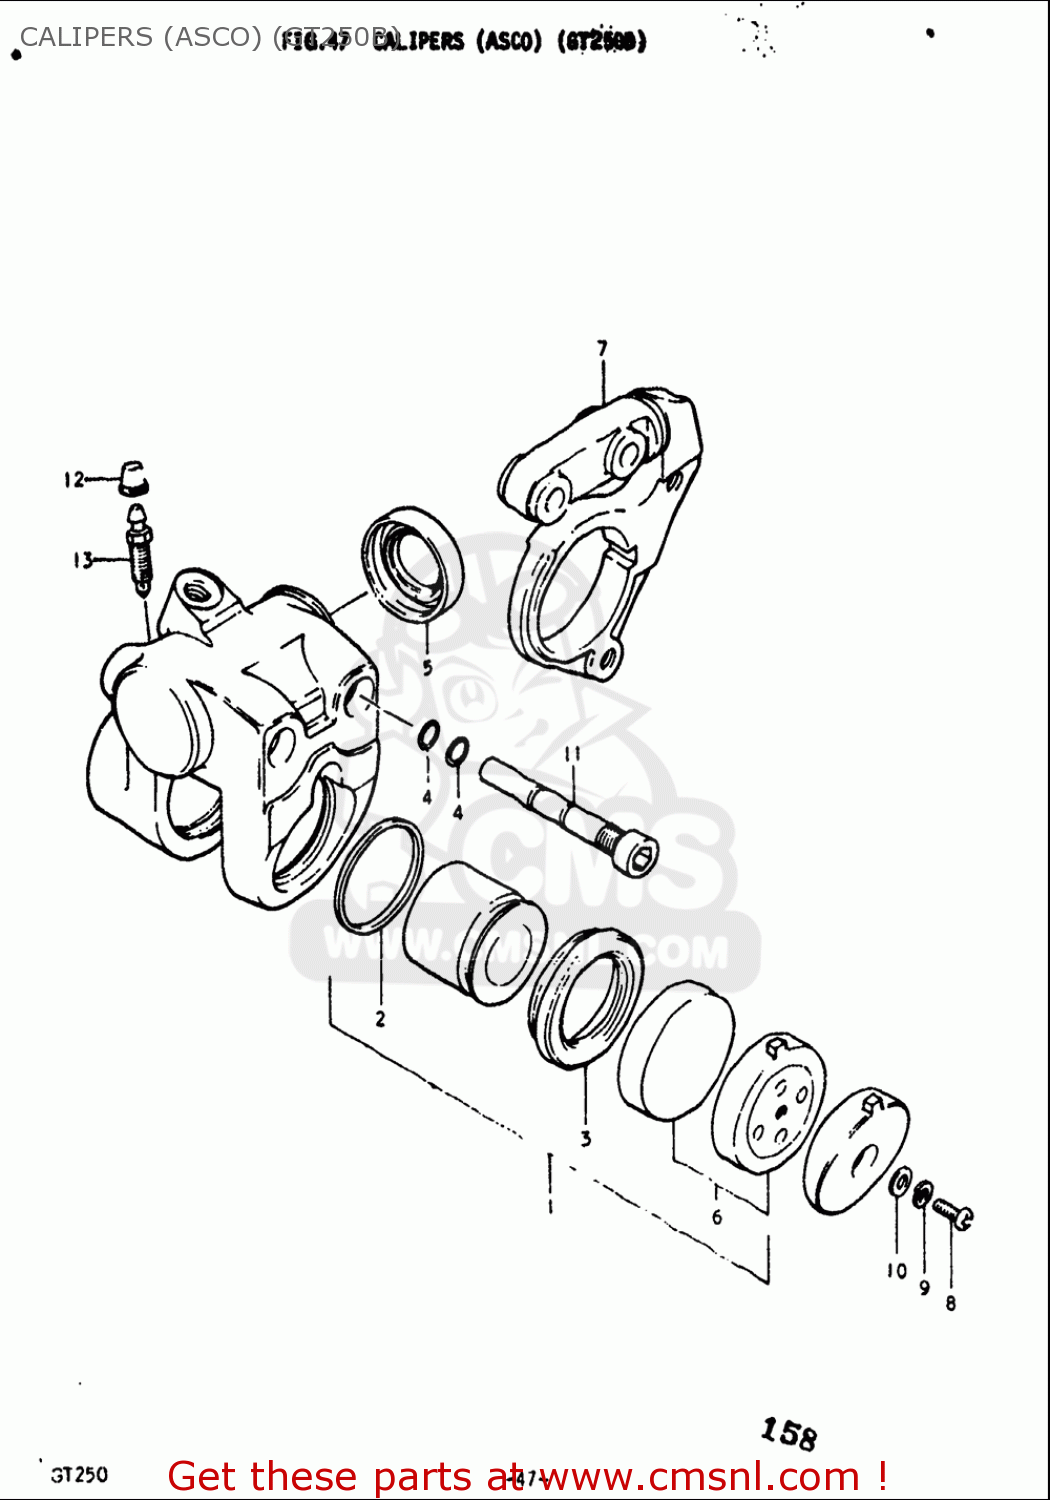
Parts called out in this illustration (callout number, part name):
2	SEAL,PISTON
3	BOOT,PISTON
4	O RING,AXLE CALIPER
5	BOOT,HOLDER
7	HOLDER,CALIPER
8	SCREW
9	WASHER,LOCK
10	WASHER
11	AXLE,CALIPER
12	CAP,BLEEDER PLUG
13	BLEEDER
